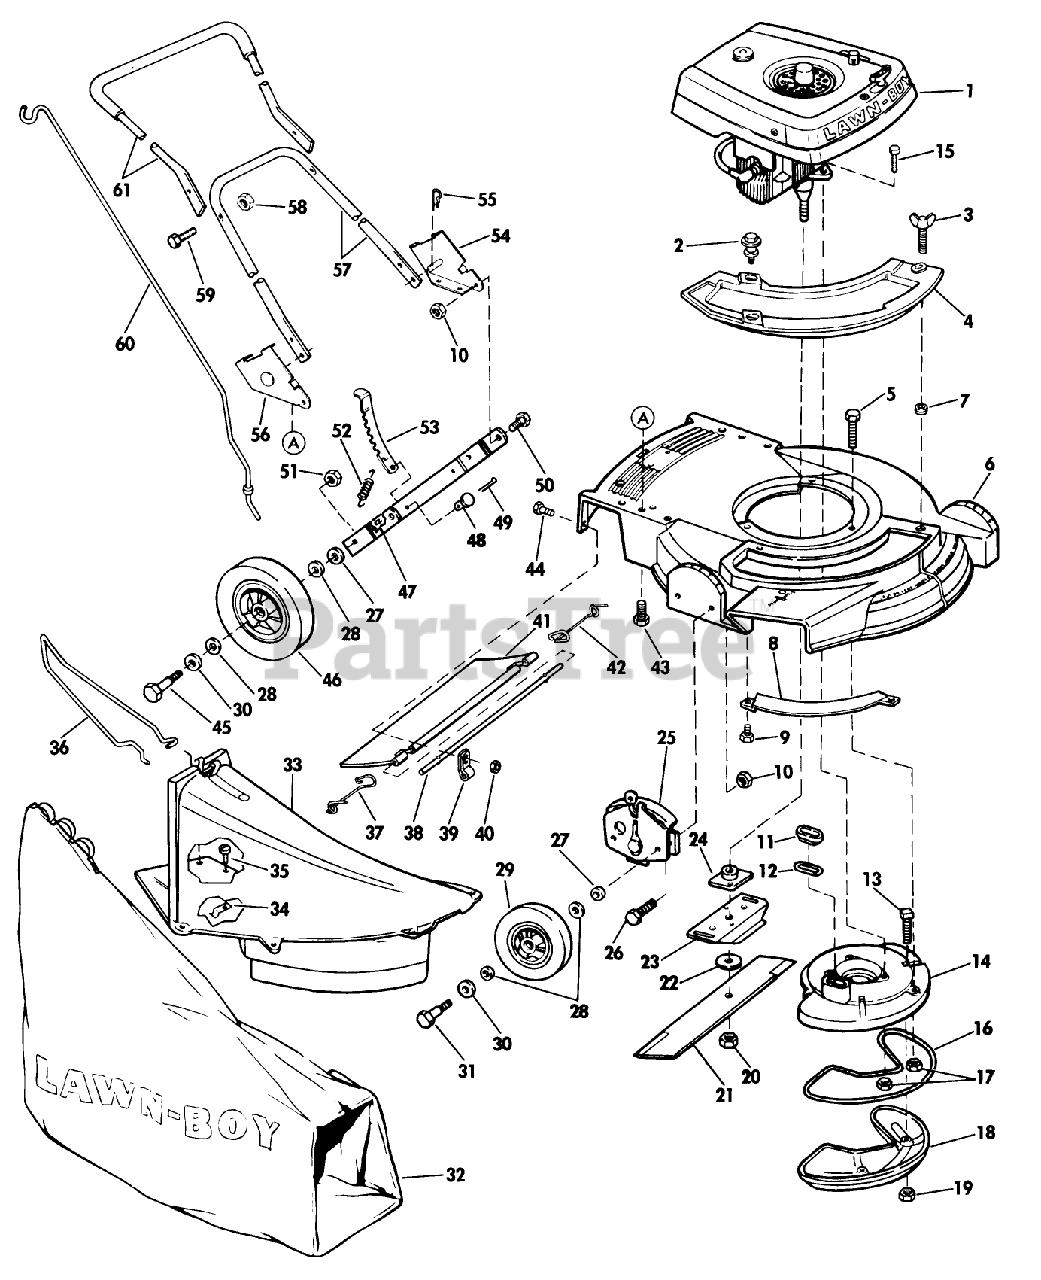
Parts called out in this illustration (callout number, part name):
3	WING SCREW LAWRE
5	SCREW
8	TOE BAR 19"
8	BAR-TOE
10	NUT
11	SLEEVE
12	GASKET S
17	NUT-LOCK F
20	NUT-BLADE
22	WASHER
24	PLATE AND COLLAR ASM
27	WASHER WROUGHT
28	WASHER
30	SPACER
31	BOLT WHEEL
32	89802 LB WHOLE GOODS
37	SPRING;TRAILING SHIELD RH
38	ROD T/SHIELD ADV WIRE
38	ROD 21" ADVANCE
39	CLAMP ROD KMC
42	SPRIG T/SHLD ASOC
43	SCREW
45	BOLT
50	BOLT-SHOULDER
51	LOCKNUT
52	SPRING N.A.S
55	HAIR PIN
59	SCREW
60	ROD GRASSBAG
